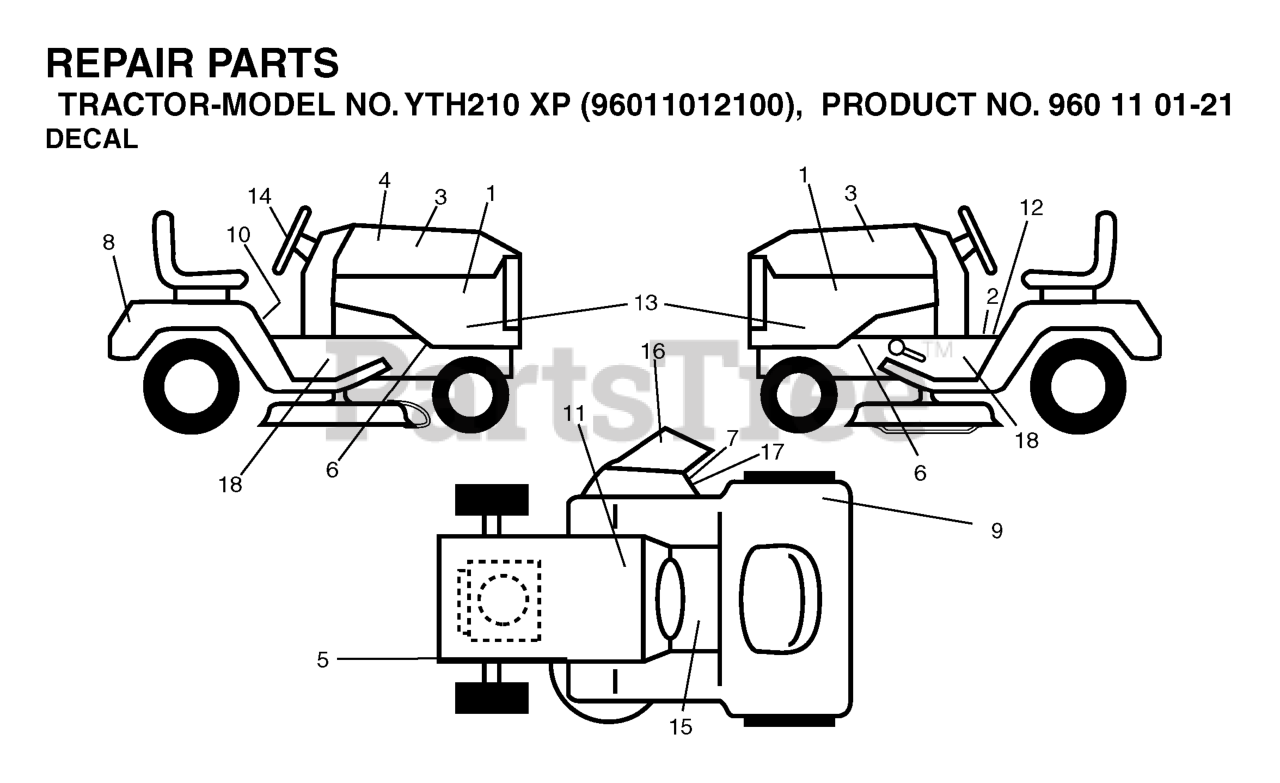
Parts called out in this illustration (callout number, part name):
1	DECAL.HOOD.HUSQVARNA.INTERNATI
2	DECAL PARK BRAKE
5	DECAL V BELT SCHEMATIC
7	DECAL.INTERNATIONL.CUTFINGER
9	Decal, Fender 100 DB/CE
10	LABEL
11	DECAL BTRY SYMBOLS
12	DECAL
14	DECAL.STEERING.HUSQ.BLUE
15	DECAL
16	DECAL DECK "B" 42"
17	DECAL, DEFLECT WARNING
